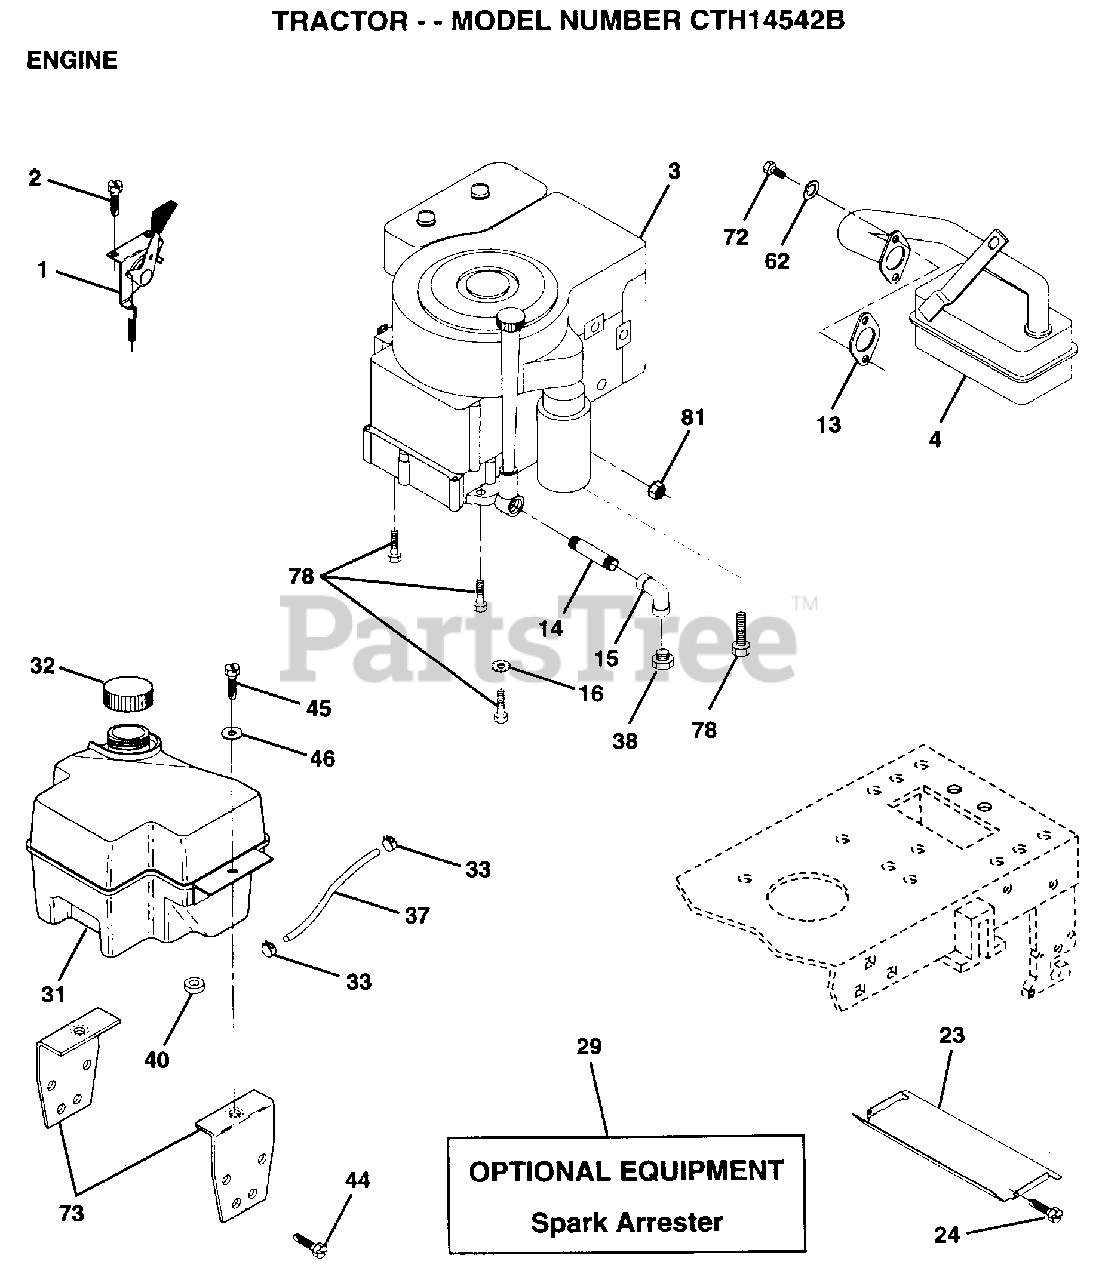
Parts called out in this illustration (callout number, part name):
1	CONTROL.THTL.19.6
2	SCREW LT
4	MUFFLER
13	GASKET ENG 1 313 LD TIN PLATED
14	PIPE NIPPLE
15	ELBOW
16	LOCKWASHER
23	HEAT SHIELD
24	SCREW
32	CAP ASM FUEL
33	HOSE CLAMP
37	LINE FUEL
44	SCREW
45	SCREW HEX CRT
46	WASHER
62	LOCKWASHER
72	SCREW
73	BRACKET.SUPT.TANK
78	SCREW
81	NUT
